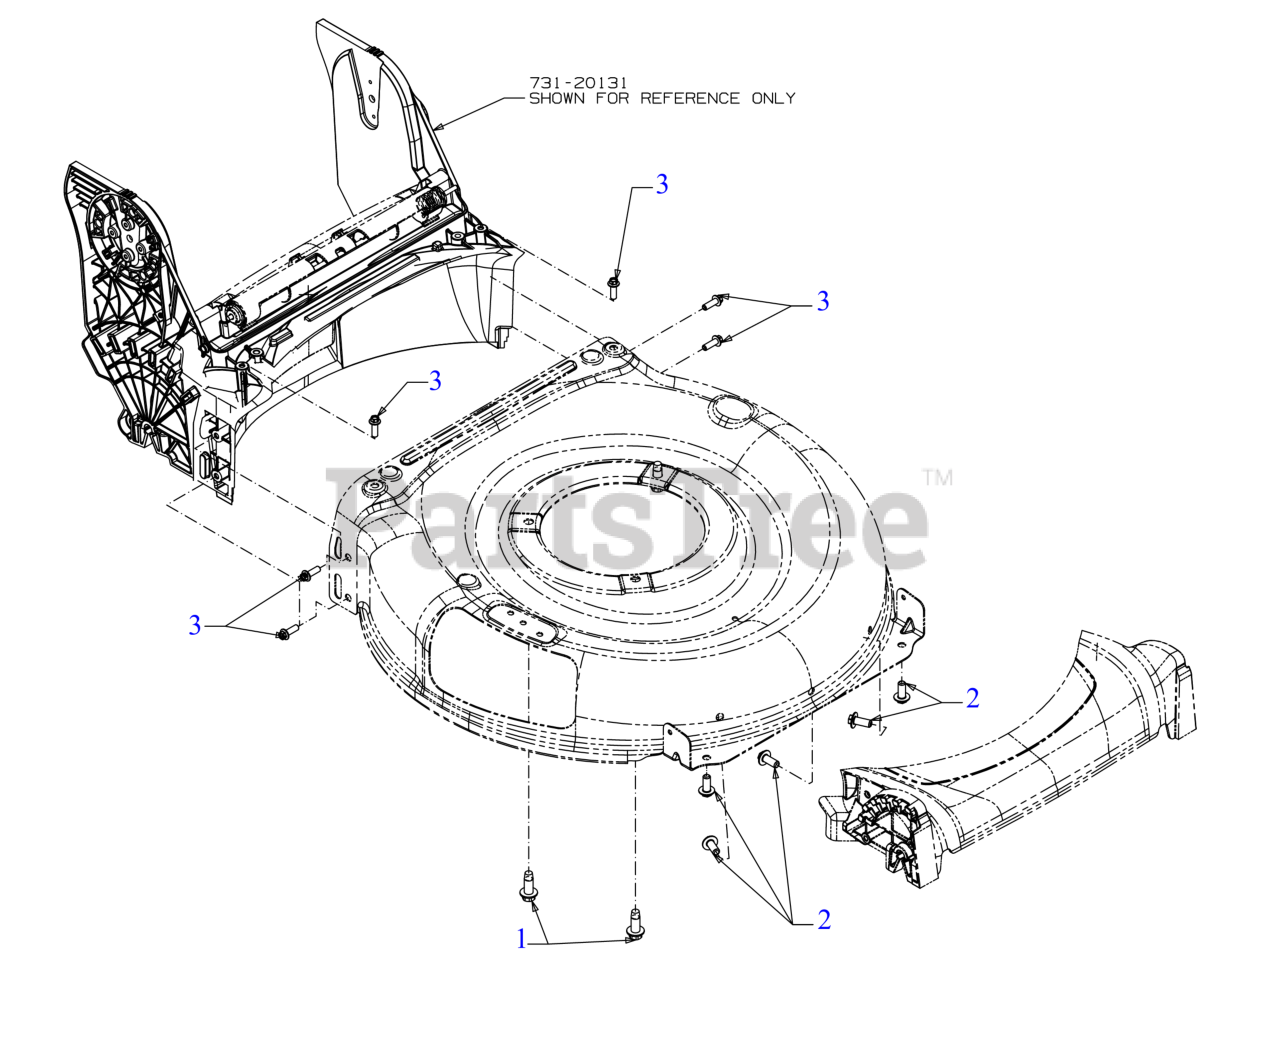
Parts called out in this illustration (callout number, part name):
1	SCREW 3/8-16 x 1
2	SCREW 5/16-14 x .750
3	SCREW 1/4 x .750
